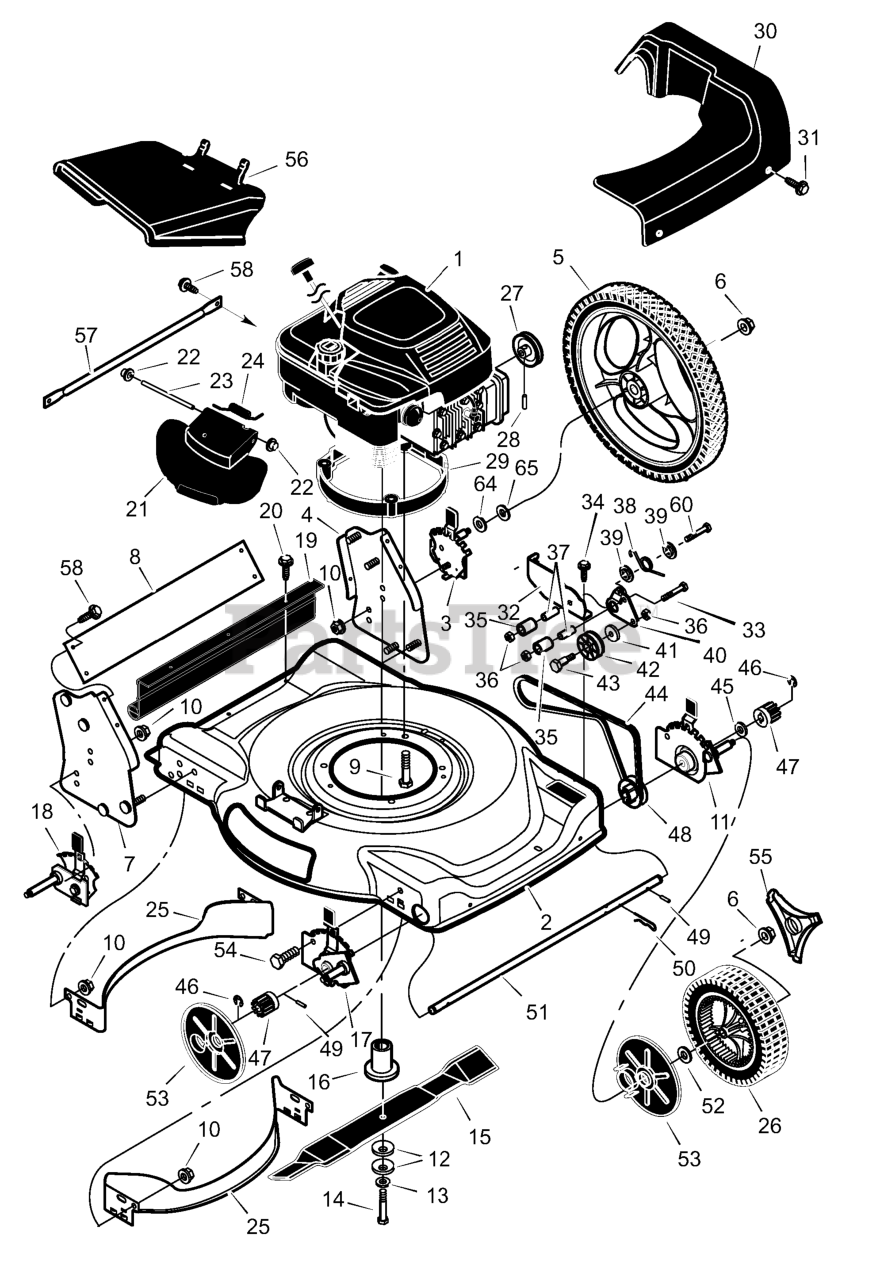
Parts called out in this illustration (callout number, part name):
1	Engine *
2	Housing
3	Height Adjuster, Left Rear
4	Bracket, Left Handle
5	Wheel and Tire, Rear
6	Locknut, Flange
7	Bracket, Right Handle
8	Brace, Handle Bracket
9	Bolt, Engine
10	Nut
11	Height Adjuster, Left Front
12	Washer, Belleville
14	Bolt, Hex
16	Adapter, Blade
17	Height Adjuster, Right Front
18	Height Adjuster, Right Rear
19	Guard, Rear
21	Cover, Mulcher
22	Push-On Cap
23	Pin, Pivot
26	Wheel and Tire, Drive
28	Pin, Spring
29	Base, Engine
30	Cover, Belt
32	Bracket, Idler Support
35	Idler, Backside
36	Locknut
37	Bearing
40	Arm, Pivot
42	Pulley, Idler
43	Bolt, Shoulder
46	Ring, Retainer
47	Gear, Pinion
49	Pin, Drive
50	Pin, Hair
52	Washer
53	Cover, Dust
54	Bolt
55	Hub Cap
56	Deflector, Chute
